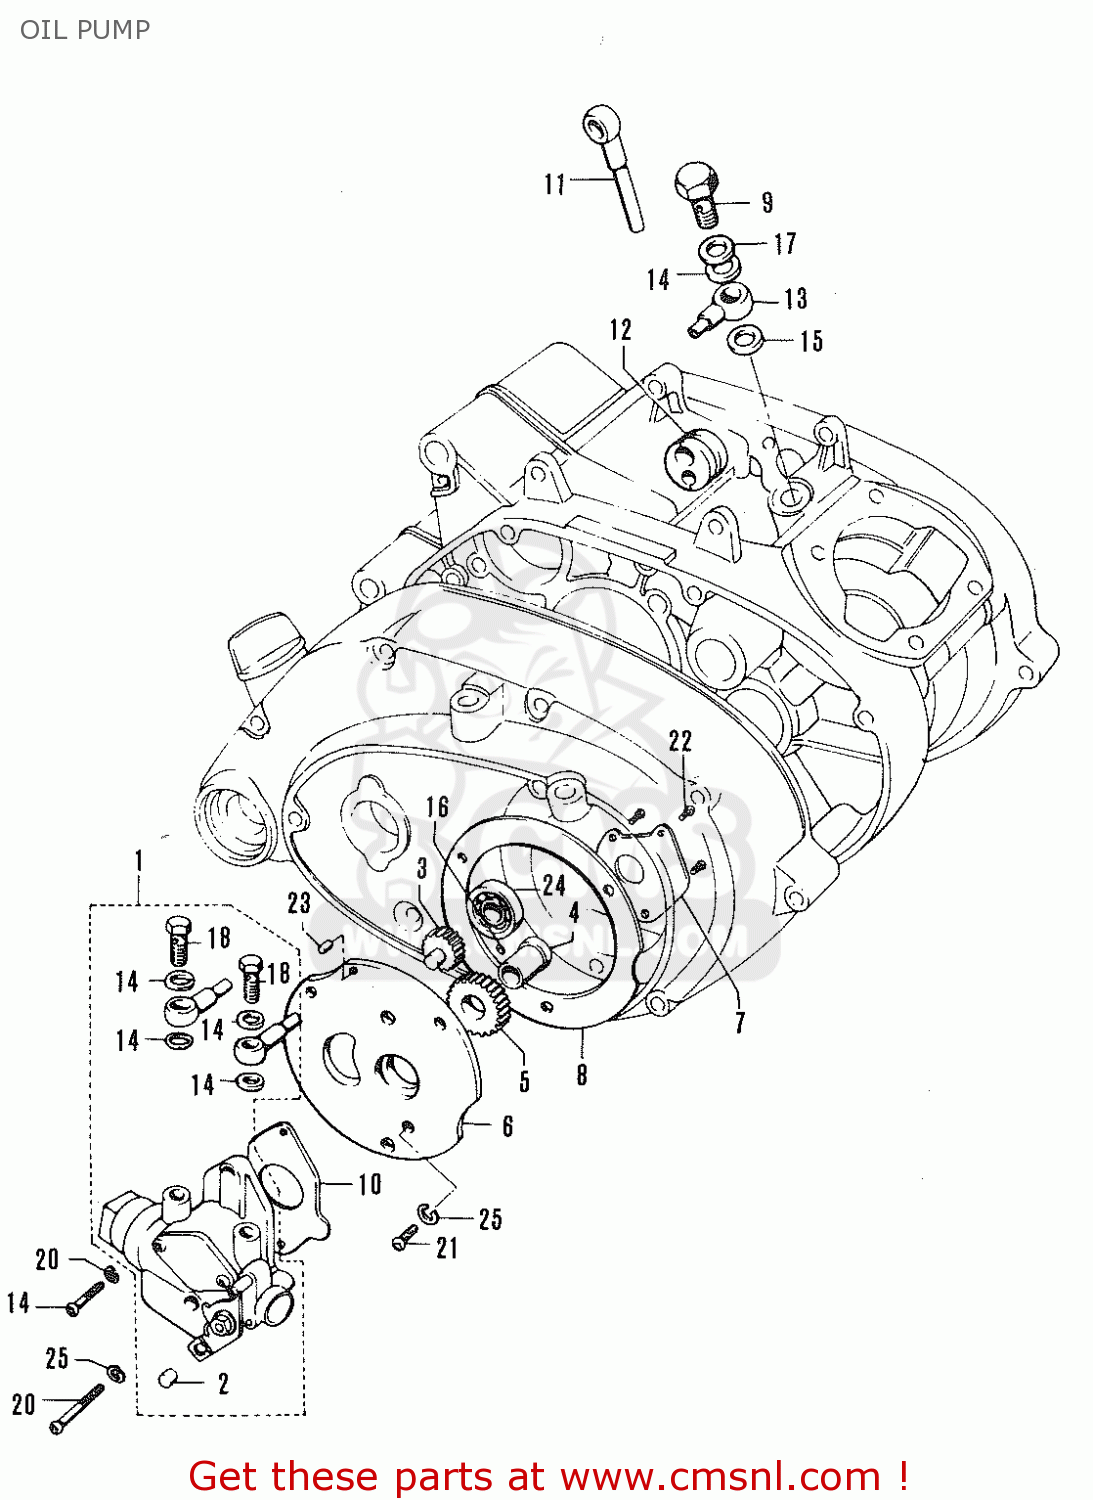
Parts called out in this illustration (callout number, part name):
1	COOLER SET,OIL
2	TERMINAL,CABLE
3	GEAR,OIL PUMP DRIVE
4	GEAR,OIL PUMP DRIVE
5	GEAR,OIL PUMP DRIVEN
6	OIL PUMP DRIVE GEAR BOX
7	PLATE,OIL PUMP GEAR BOX
8	GASKET,OIL PUMP GEAR CASE
9	VALVE,CHECK
10	GASKET,OIL PUMP (MCA)
11	HOSE,OIL NO.1
12	DUST SEAL,OIL PLUG
13	HOSE,OIL NO.2
14	GASKET (NAS)
15	GASKET(10X16X3) (NAS)
16	PIN(2X5.5)
17	O RING(D:1.3,ID:7.6)
18	UNION
19	Screw
20	SCREW
21	SCREW
22	SCREW
23	PIN
24	BALL BEARING
25	LOCK WASHER
